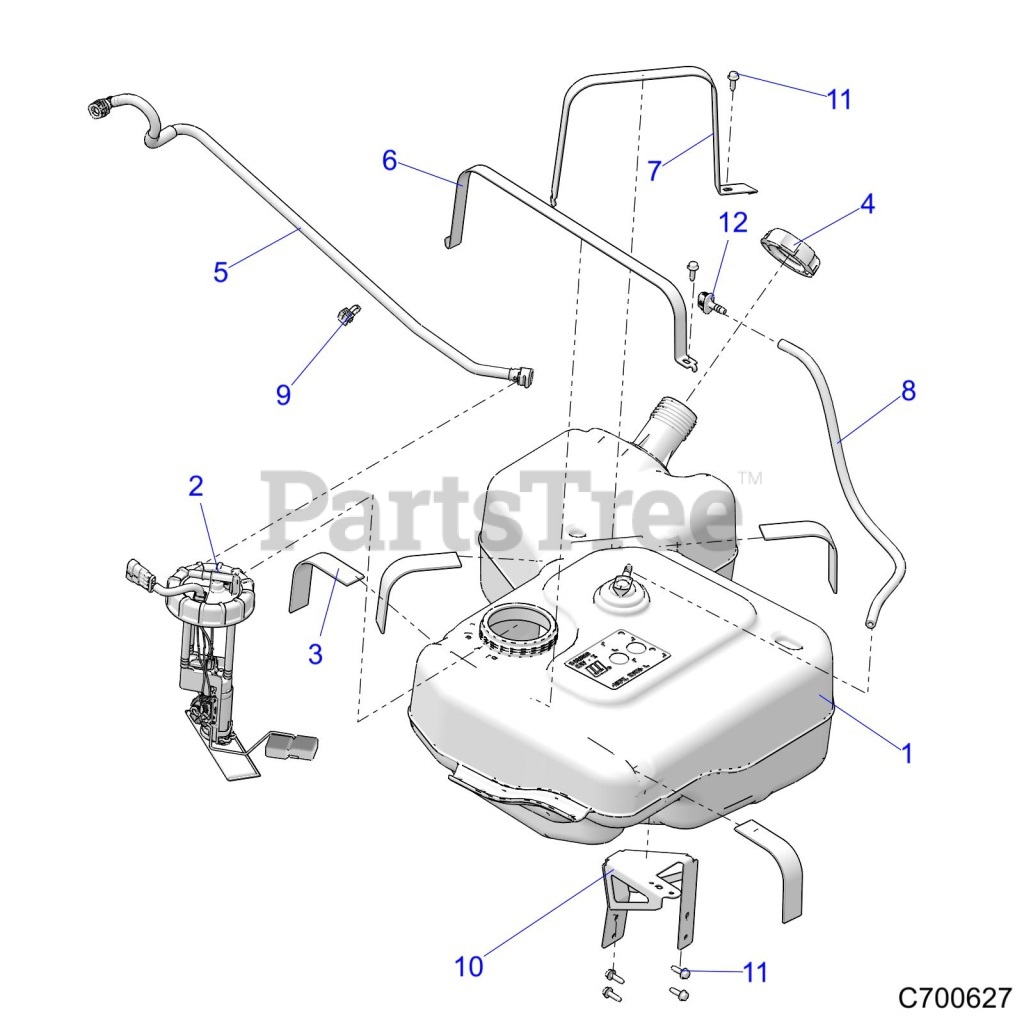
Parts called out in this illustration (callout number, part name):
1	ASM-FUEL TANK
3	PAD, BATTERY
4	CAP-GAS TANK,TETHER
5	ASM-FUEL LINE
6	BRKT-TANK,STRAP,INSIDE,GALV
7	BRKT-TANK,STRAP,OUTSIDE,GALV
8	FUEL LINE-54 CENTIMETRS
9	CLIP-EDGE,SIDE W/STRAP
10	BRKT-FUEL TANK,SUPPORT,BLK
11	SCR-M6X1.0X20,HXHD,FLG,TDFM,BL
12	FITTING-VENT LINE
